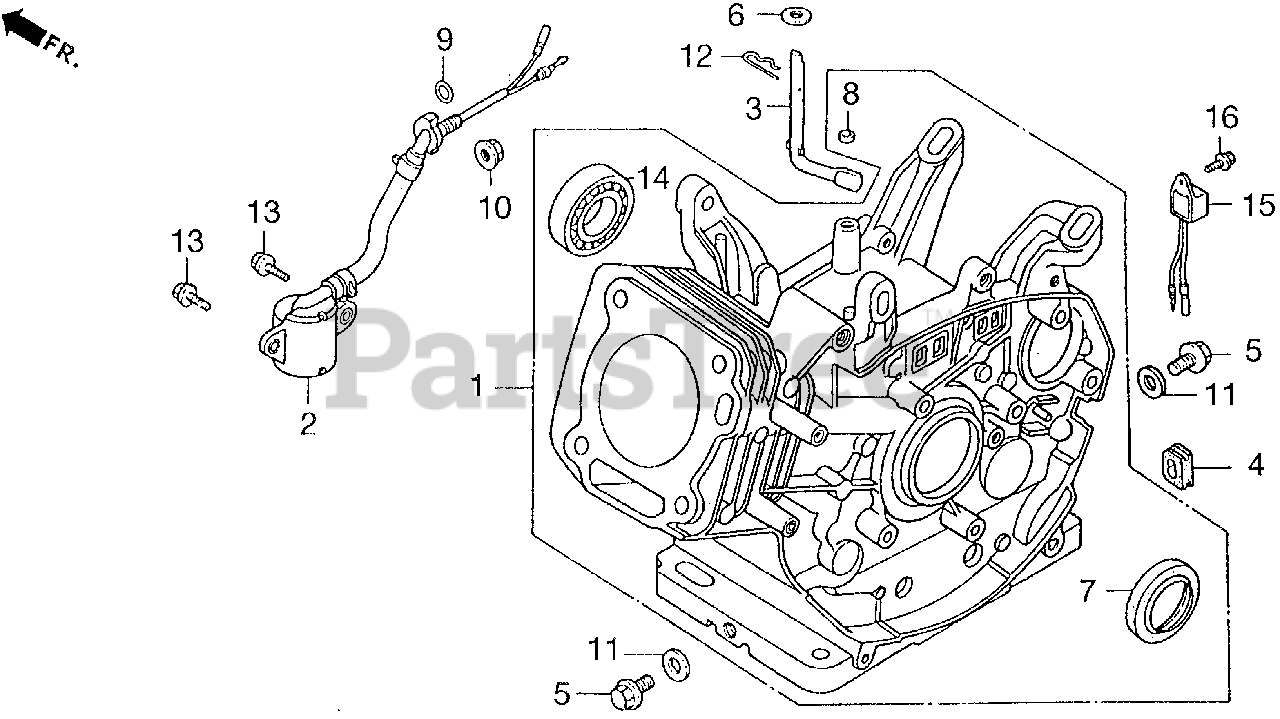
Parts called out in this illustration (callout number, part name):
1	CYLINDER ASSY.
1	CYLINDER ASSY. (ALERT)
2	SWITCH ASSY., OIL LEVEL
3	SHAFT, GOVERNOR ARM
4	GROMMET, WIRE
5	BOLT, DRAIN PLUG
6	WASHER (8.2X17X0.8)
7	OIL SEAL (30X46X8)
9	O-RING (13.5X1.5) (ARAI)
10	NUT, FLANGE (10MM)
11	WASHER, DRAIN PLUG (12MM)
12	PIN, LOCK (10MM)
13	BOLT, FLANGE (6X12)
15	ALERT UNIT, OIL
16	BOLT, FLANGE (6X12) (CT200)
